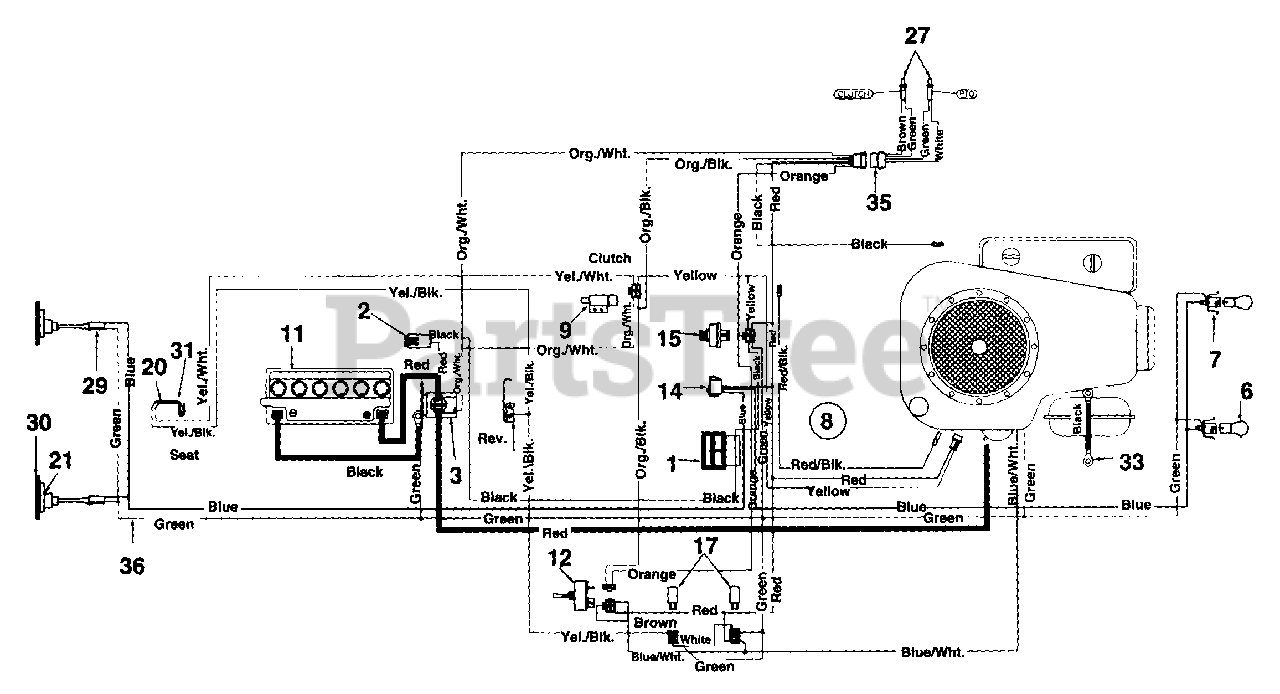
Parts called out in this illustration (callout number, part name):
1	Ammeter
2	Fuse 20 Amps
3	Solenoid
6	Bulb
7	Socket
8	Wire Harness
9	Safety Switch (Clutch)
11	Battery 12V
12	Switch (PTO)
14	Light Switch
15	Ignition Switch
17	Relay
20	Safety Switch (Seat)
21	Tail light
27	Bulb
29	Tail light Harness
30	Bulb
31	Safety Switch (Seat)
33	Wire 7.5" Lg.
35	Monitor Harness
36	Tail light Adapter Harness
